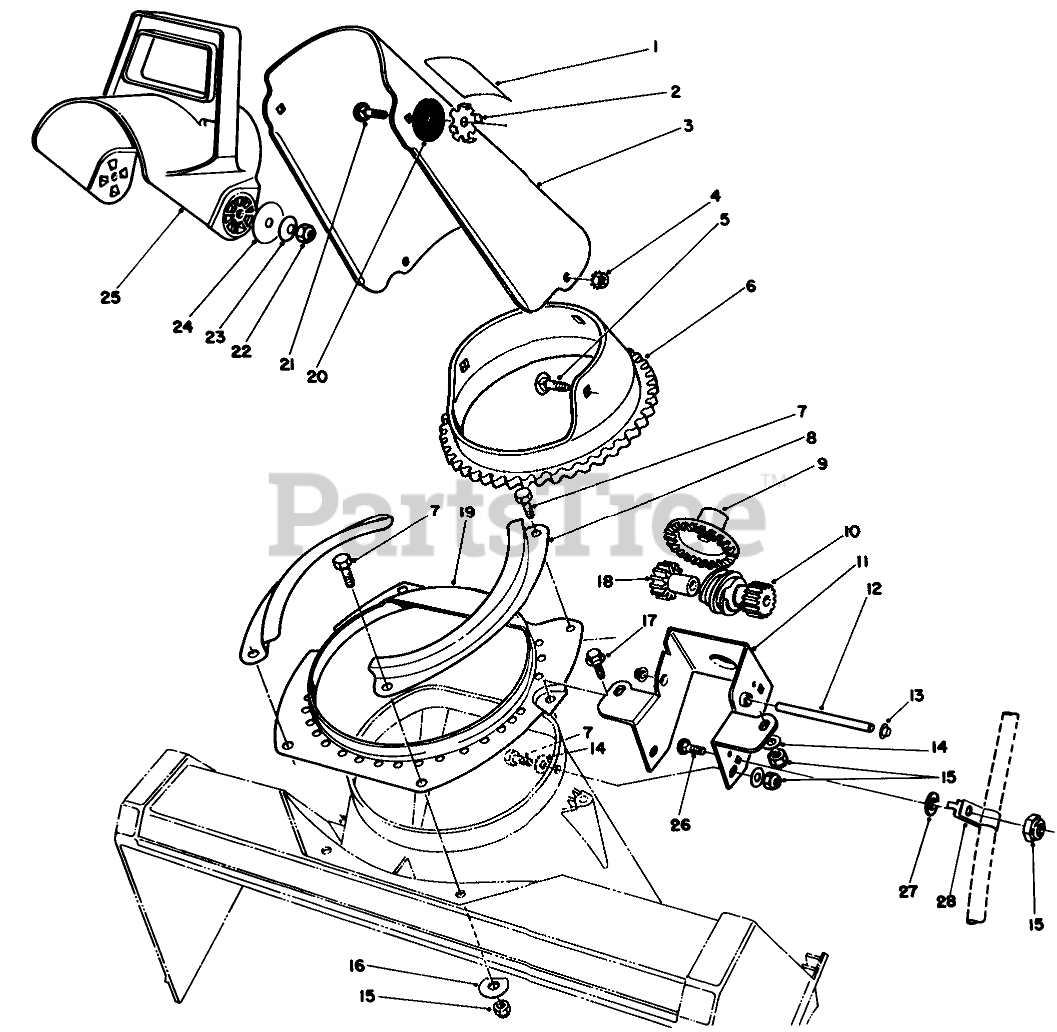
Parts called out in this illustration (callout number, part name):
1	Decal-Danger
2	PLATE-FRICTION
3	Chute-Discharge (Incl. Ref. #1)(Model #38185)
4	NUT-KEPS
5	SCREW-CARR
6	RING-GEAR, CHUTE
7	SCREW-HH
8	Retainer-Chute Ring
9	GEAR-FACE
10	GEAR-SPUR/WORM
11	Bracket-Chute Gears
12	SHAFT-GEAR, WORM
13	NUT-PUSH
14	WASHER-FLAT
15	NUT-LOCK, NI
16	Washer
17	SCREW-PLASTITE
18	GEAR-SPUR, SPACER
19	Ring-Chute Support
20	WASHER-RUBBER
21	SCREW-CARR
22	NUT-LOCK, NI
23	WASHER-BELLEVILLE
24	WASHER-FLAT
25	CHUTE-DEFLECTOR
26	SCREW-CARR
27	WASHER-PLAIN
28	ABLE CLAMP
